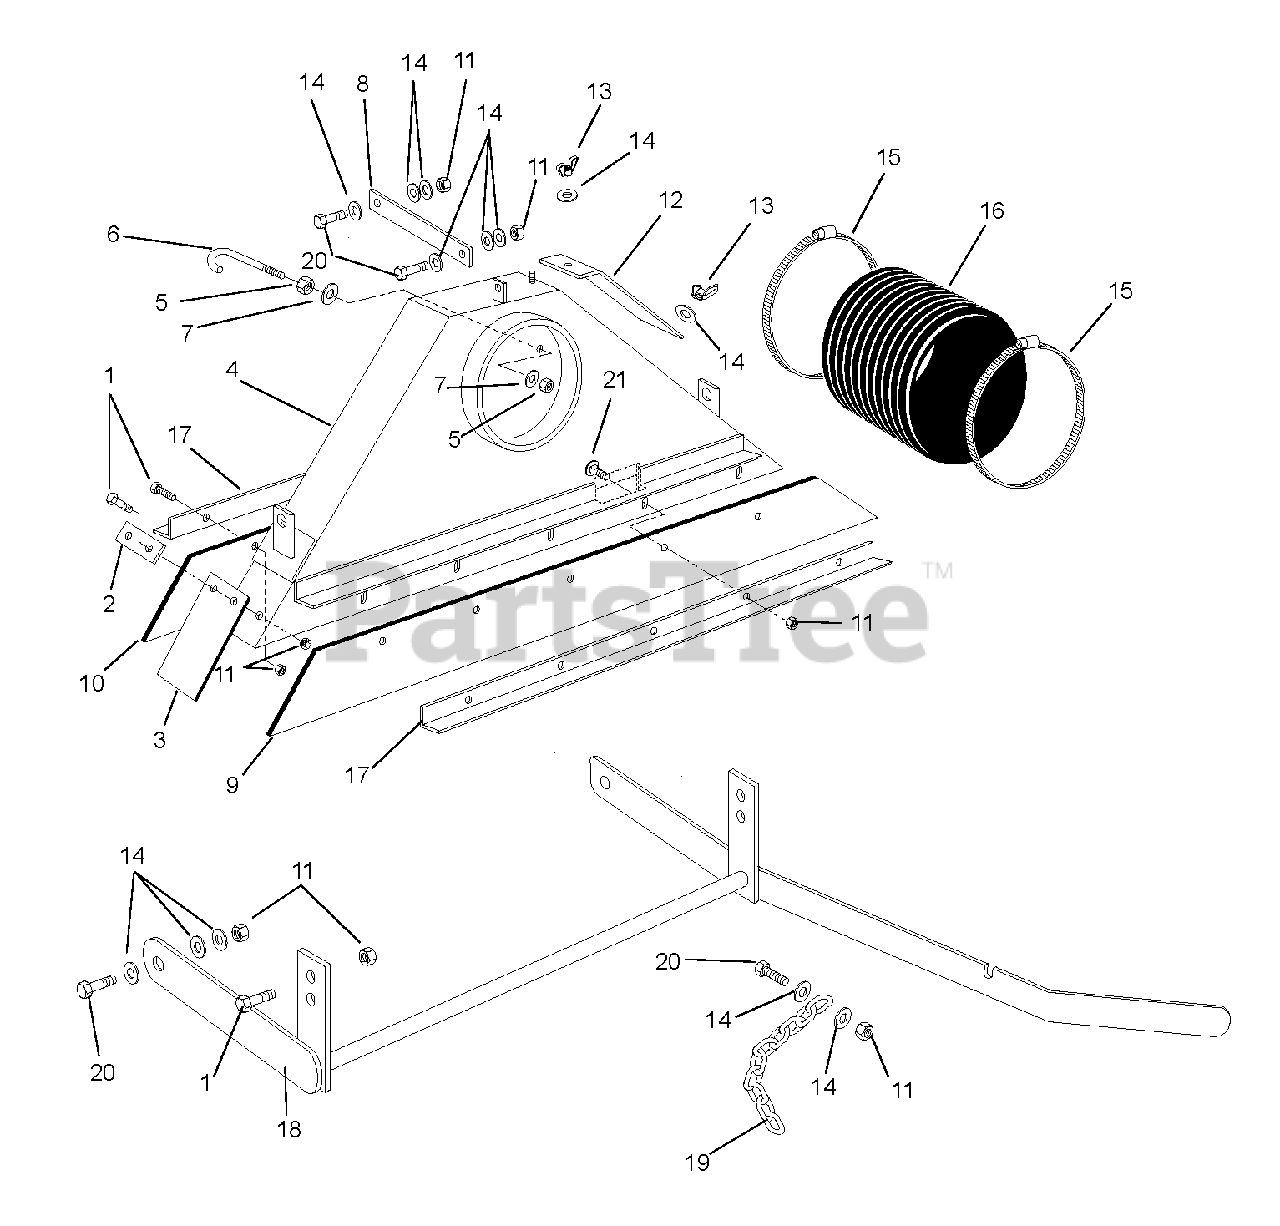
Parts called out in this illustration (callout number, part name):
1	Cap Screw, Hex Head .38-16 x 1.00
2	End, Bolting Strip
3	End Cap, Flex Skirt
4	Weldment, Scoop
5	Nut, Hex .50
7	Washer, Flat .50
8	Brace, Scoop Stabilizer
9	Flex Skirt, Front
10	Flex Skirt, Rear
11	Nut, Nylock .38-16
12	Side Cover, Scoop
13	Wing Nut, .38-16
14	Washer, Flat .38
15	Clamp, Worm Drive 13 Inch
16	Hose, Flex 12 Inch
17	Retainer Strip
18	Weldment, Lift
19	Chain .25 Ten Link
20	Cap Screw, Hex Head .38-16 x 1.25
21	Bolt, Carriage .38-16 x 1.00
